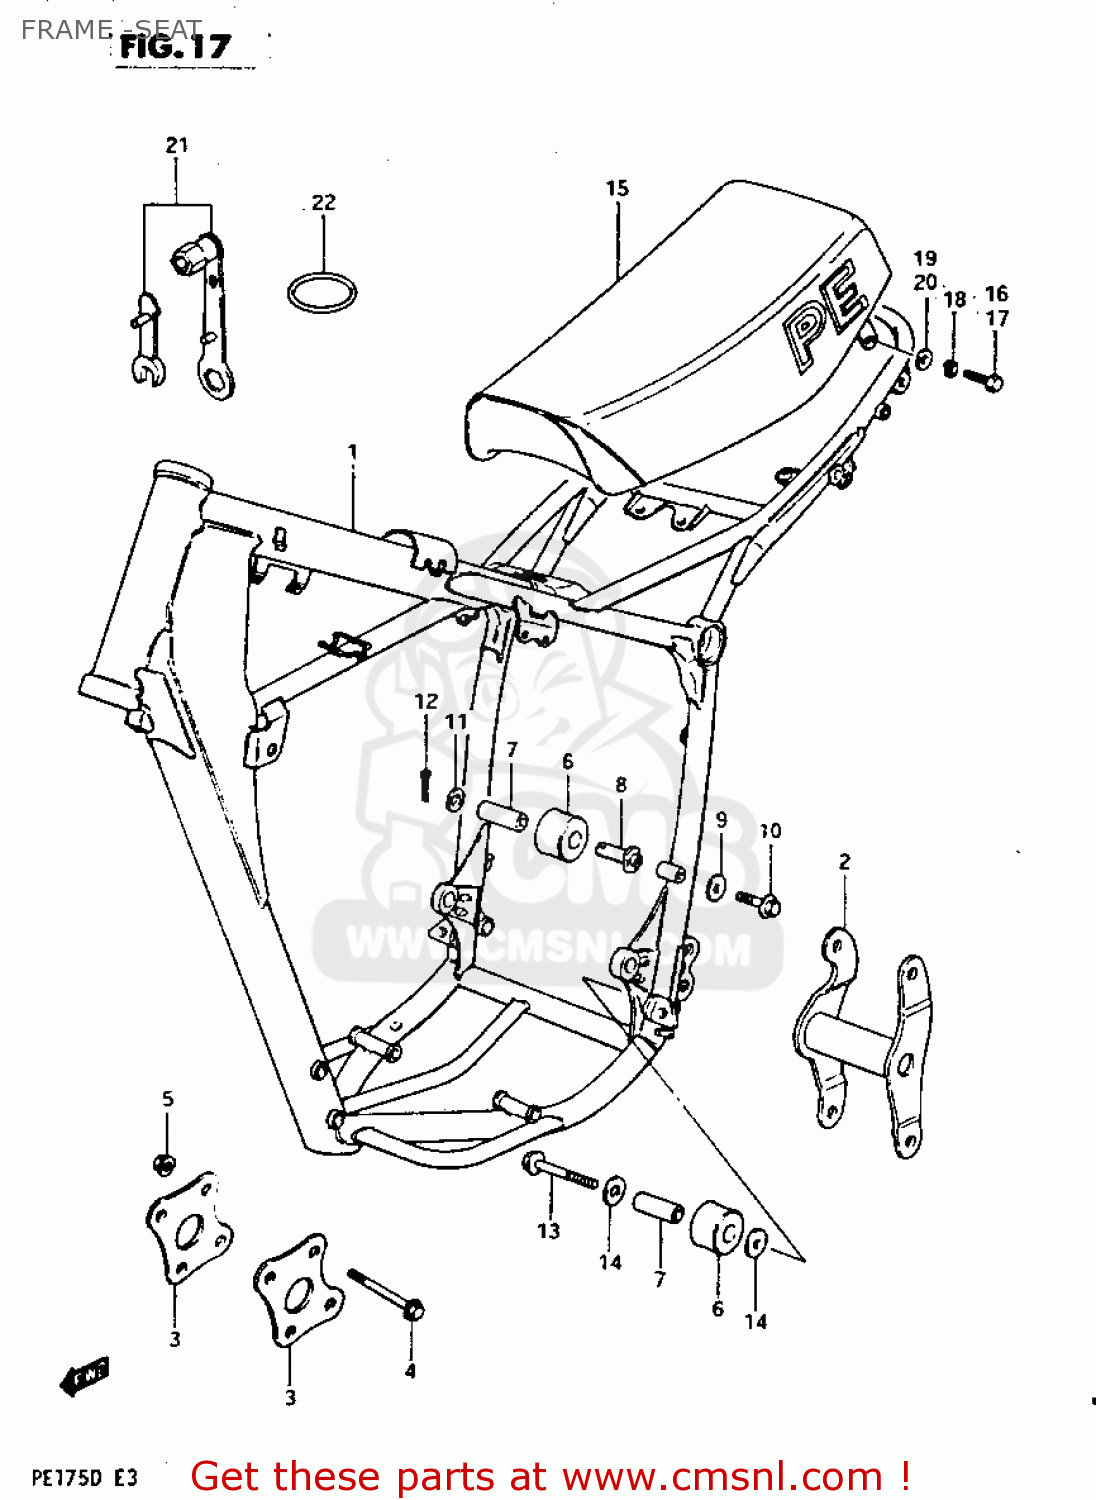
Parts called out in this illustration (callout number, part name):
1	FRAME
2	PLATE,ENGINE MOUNTING
3	PLATE,ENGINE MOUNTING
4	BOLT(8X67)
5	NUT
6	ROLLER,CHAIN LENGTH CONTROL
7	SPACER,CHAIN LENGTH ROLLER
8	BOSS,CHAIN LENGTH ROLLER
9	WASHER
10	BOLT
11	WASHER
12	PIN 25X20
13	BOLT(8X45)
14	WASHER
15	SEAT ASSEMBLY
16	BOLT
17	BOLT 8X45
18	LOCK WASHER
19	WASHER (8.5X20X2.6)
20	WASHER (8.7X22X2)
21	SPARK PLUG WRENCH
22	O RING TOOL FITTING
